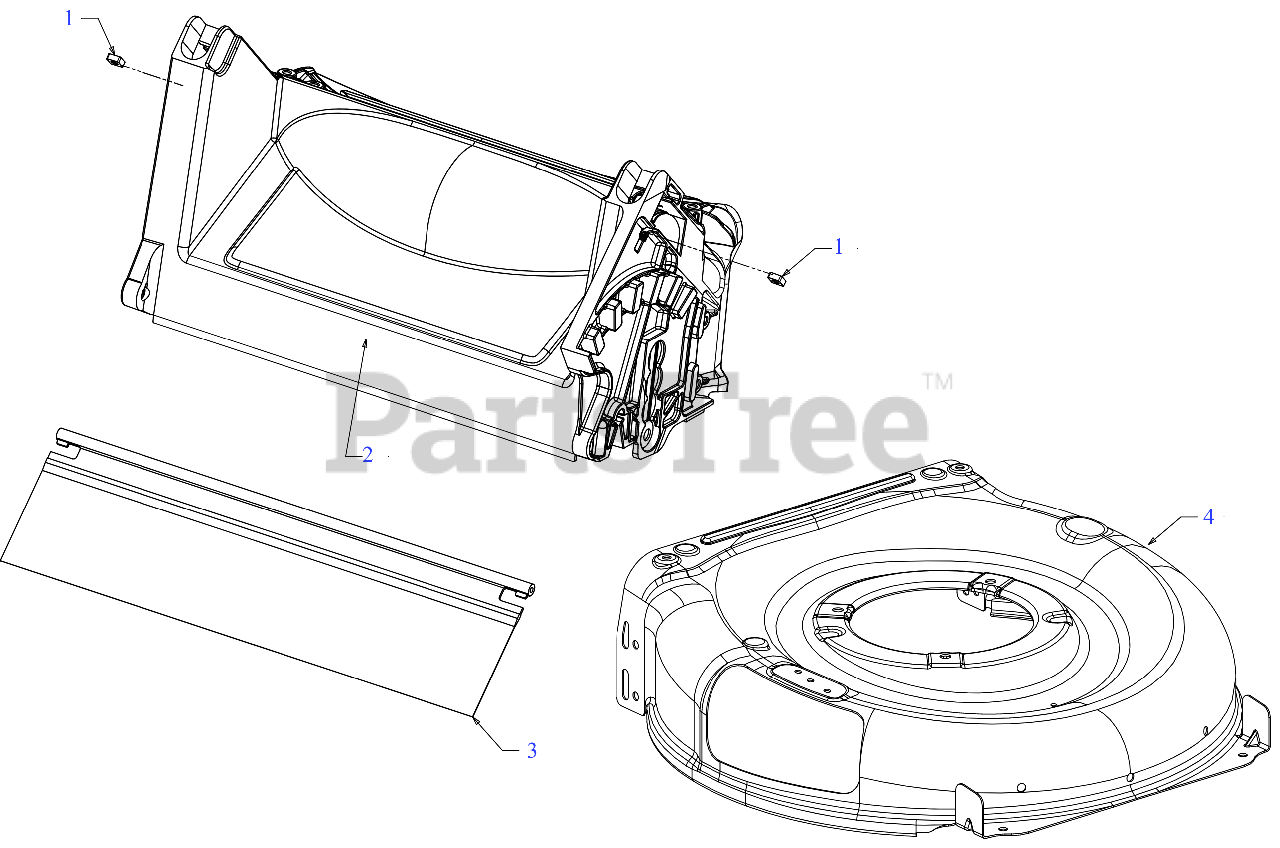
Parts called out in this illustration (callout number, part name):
1	SQUARE NUT 1/4-20
2	REAR BAFFLE ASSEMBLY (2N1)
3	TRAILSHIELD
